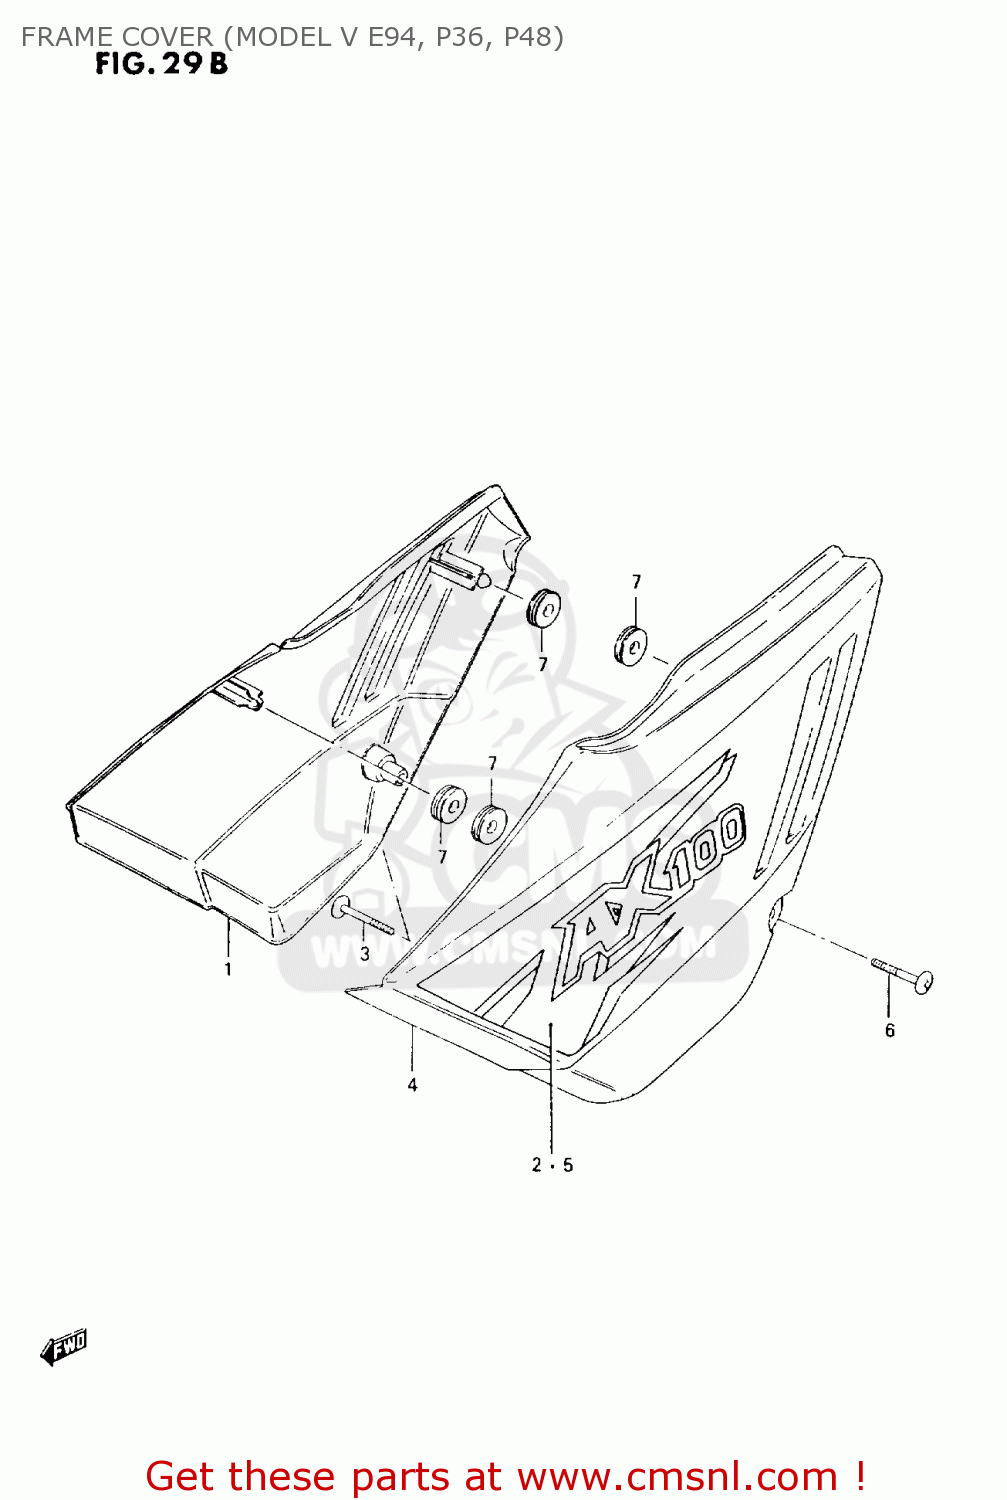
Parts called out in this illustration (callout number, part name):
1	COVER, FRAME RH (RED)
2	TAPE, RH
3	SCREW
4	COVER,FRAME,L(RED)
5	TAPE, LH
6	SCREW(6X45)
7	CUSHION
